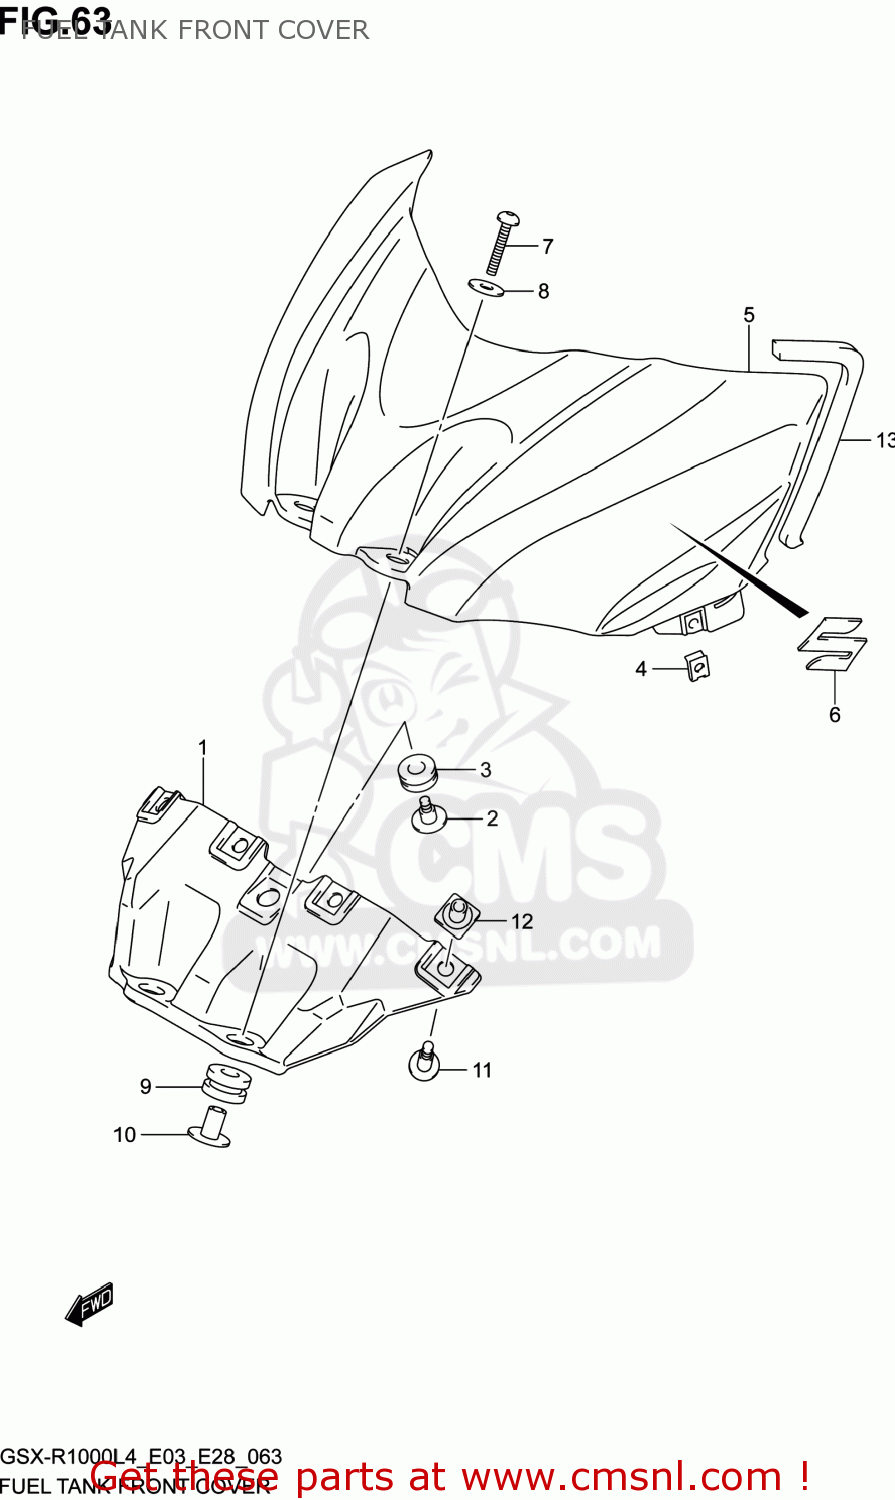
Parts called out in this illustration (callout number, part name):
1	BRACKET,FUEL TANK FR
2	SCREW(5X16.4)
3	CUSHION
4	NUT
5	COVER,FUEL TANK FR
6	EMBLEM, S
7	SCREW(6X40)
8	WASHER(6,5X22X1.6)
9	CUSHION
10	SPACER,FUEL TANK FR
11	SCREW(6X10)
12	NUT(M6)
13	CUSHION,FUEL TANK COVER
